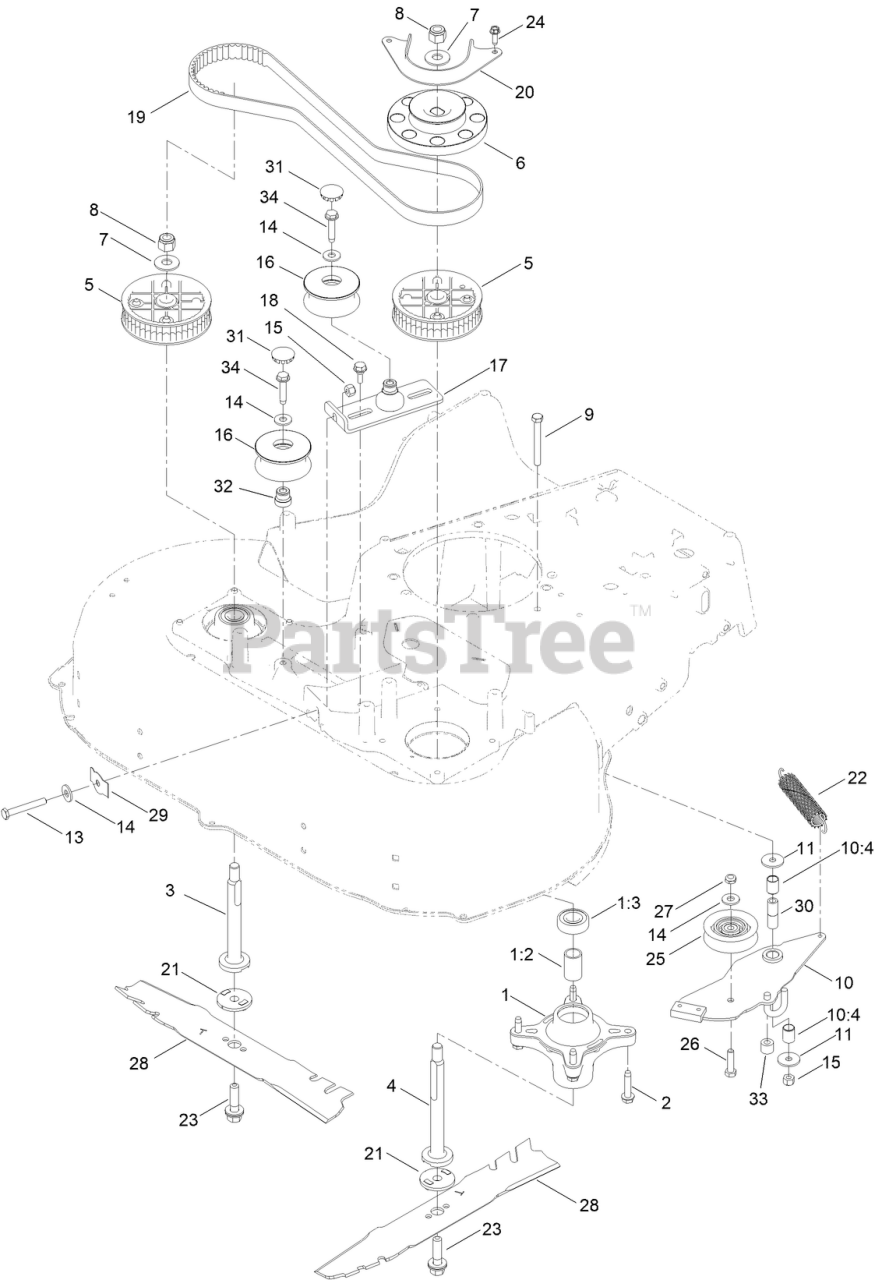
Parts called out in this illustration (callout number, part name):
1	SPINDLE ASM
1:2	SPACER
1:3	BEARING-BALL
2	SCREW-THD ROLL, HWH
3	SHAFT-SPINDLE
4	SHAFT-SPINDLE
5	SPROCKET
6	PULLEY-BRAKE, SPINDLE
7	WASHER-SPRING
8	NUT-HEX
9	SCREW-HH
10	BRAKE ARM ASM
10:4	BUSHING-SLEEVE
11	WASHER-PIVOT
13	BOLT-TAP, HH
14	WASHER-FLAT
15	NUT-LOCK, NI
16	PULLEYS AND IDLER KIT
17	BRACKET-IDLER
18	SCREW-SHOULDER,HWH
19	BELT-SYNCHRONOUS
20	GUIDE-BELT, SPINDLE
21	ADAPTER-BLADE
22	SPRING-EXTENSION, BRAKE
23	BOLT-BLADE
24	SCREW-HWHTF
25	PULLEY-IDLER
26	SCREW-HH
27	NUT-LOCK, NI
28	BLADE-ATOMIC, 15.4 INCH
29	SPRING-FLAT
30	SPACER-BRAKE
31	PLUG-BUTTON
32	ADAPTER-BORE
33	HOSE-COOLANT
